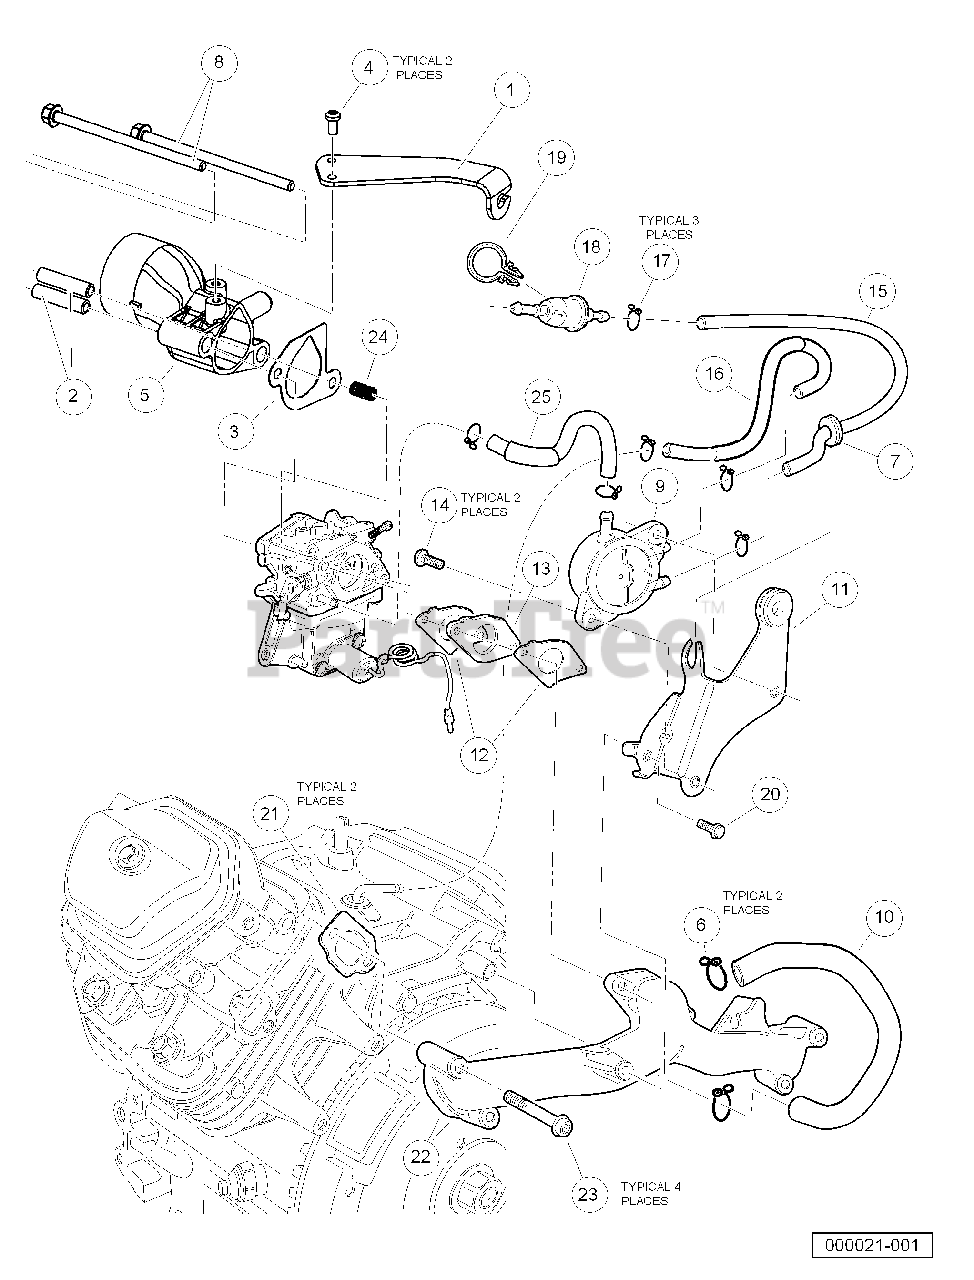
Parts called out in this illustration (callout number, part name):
1	Bracket, Choke Cable
2	Insert, Adapter, Carburetor
3	Gasket, Adapter, Carburetor
4	Screw Tapping, M5 X 0.8x10
5	Adapter, Intake Honda GX620
6	Clip, Breather Tube
7	Grommet, Reserve Tank
8	Bolt, Flange Head, M6 X 1 X 120
9	Pump Assy., Fuel, Sup
10	Tube, Breather
11	Stay, Fuel Pump
12	Gasket, Carburetor
13	Insulator, Carburetor
14	Srew-Washer, M6 X 16
15	Tube B, Fuel
16	Tube, Diaphragm
17	Clip, Tube, B10
18	Filter, Fuel
19	Clip, Wire Harness
20	Bolt, Flange Head, M6 X 11 X 4
21	Gasket, Intake Manifold
22	Manifold, Inlet
23	Bolt, Socket, M8 X 1.25 X 45
24	Spring, Continuity, Solenoid
25	Tube A, Fuel
